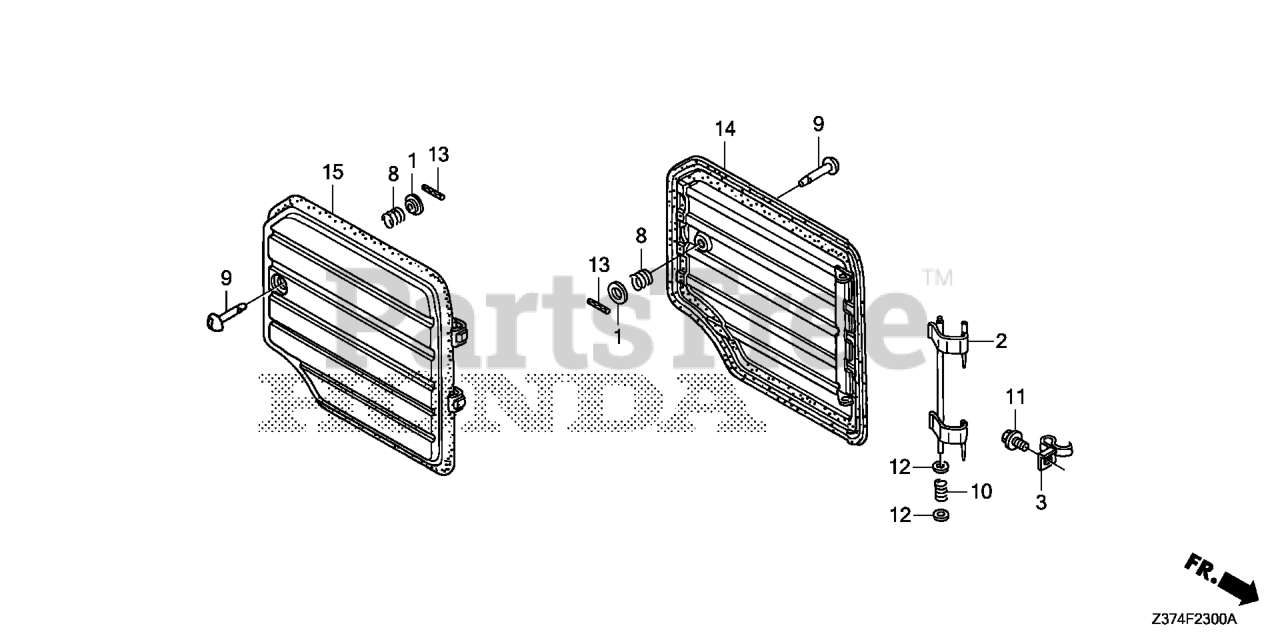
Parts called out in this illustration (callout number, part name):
1	RETAINER, LOCK SPRING
2	HINGE, R. MAINTENANCE COVER
3	SPRING, HINGE PLATE
8	SPRING, COVER LOCK
9	PIN, COVER LOCK
10	SPRING, MAINTENANCE COVER
11	BOLT, FLANGE (5X8)
12	WASHER (8MM)
13	PIN, SPRING (4X20)
14	COVER ASSY., R. MAINTENANCE *R280* (POWER RED)
15	COVER ASSY., L. MAINTENANCE *R280* (POWER RED)
